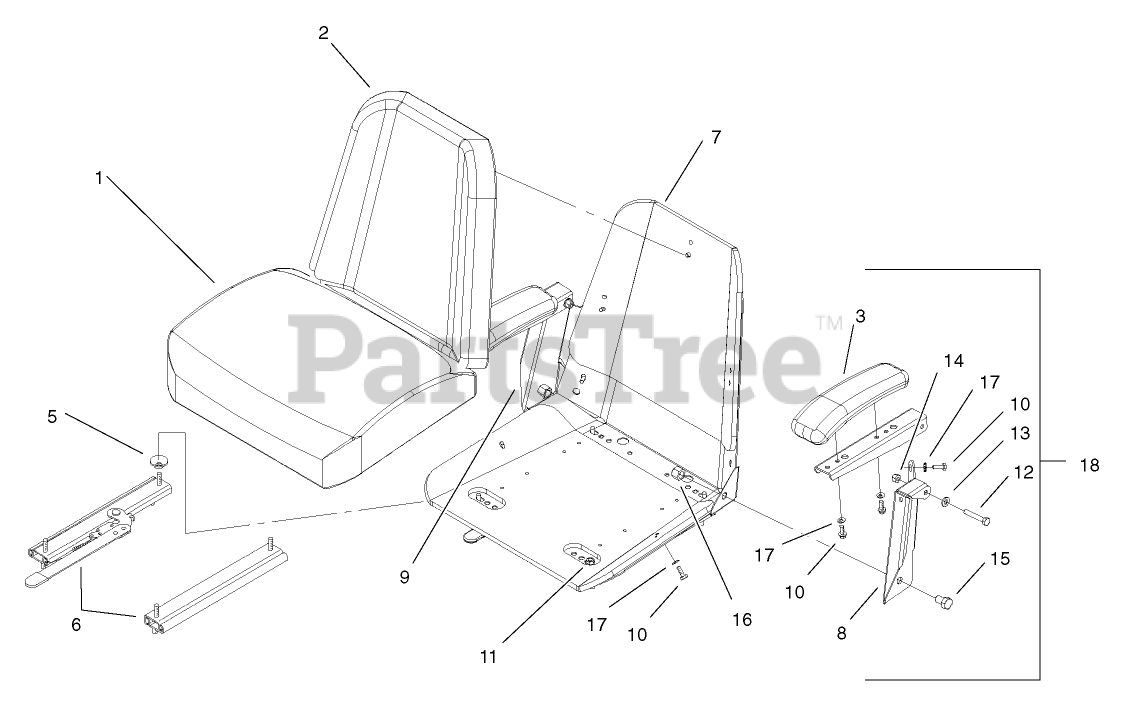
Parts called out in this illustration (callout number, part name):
1	CUSHION-SEAT, BOTTOM
2	CUSHION-SEAT, BACK
3	CUSHION-ARMREST
5	SPACER-TRACK
6	TRACK-SEAT
7	FRAME-SEAT
8	Bracket-Armrest, LH
9	Bracket-Armrest, RH
10	SCREW-HH
11	NUT-HF
12	SCREW-HH
13	WASHER-PLAIN
14	NUT-LOCK, NI
15	SCREW-HH
16	NUT-LOCK, NI
17	WASHER-FLAT
18	ARMREST KIT
